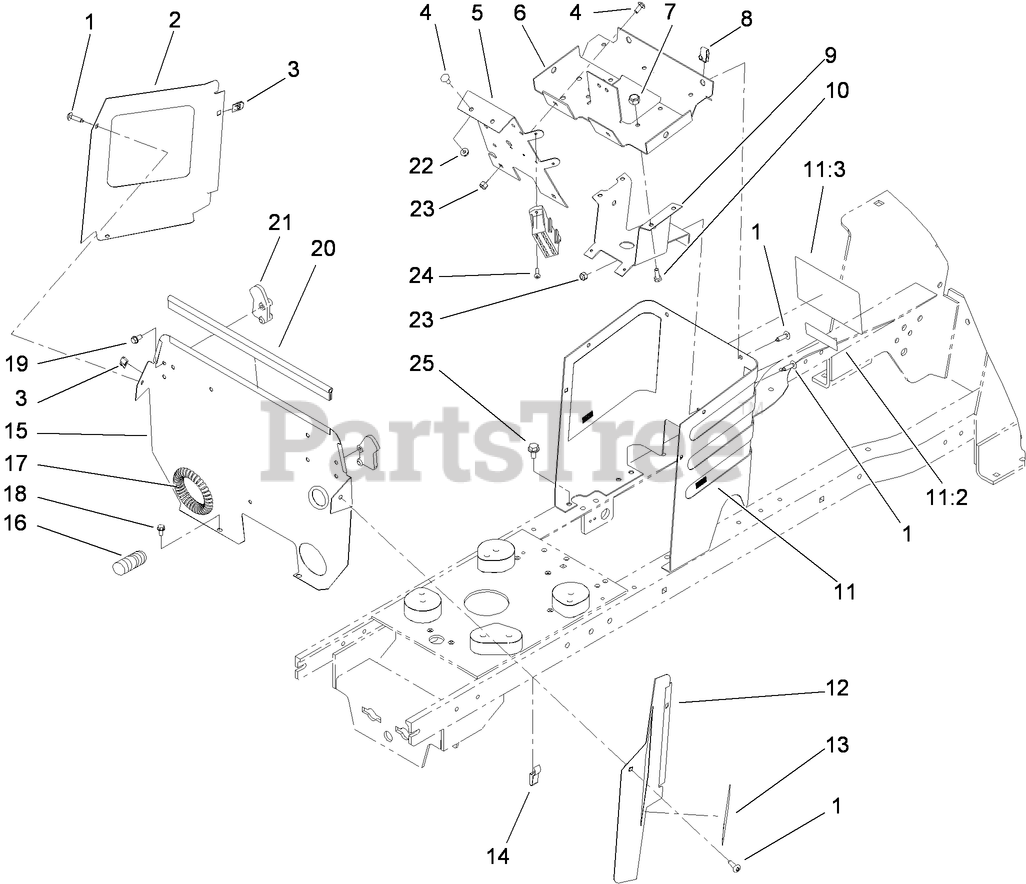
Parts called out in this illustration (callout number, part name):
1	SCREW-HH
2	RH SIDE COVER ASM
4	SCREW-CARR
5	PANEL-SUPPORT, DASH
6	SUPPORT-DASH
7	NUT-HEX
9	BRACKET-COLUMN, LOWER
10	SCREW-HH
11	HOODSTAND W/DECALS ASM
11:2	DECAL-INSTRUCTION
11:3	DECAL-DANGER
12	LH COVER ASM
14	CLAMP-CASING
17	COVER-SHAFT, DRIVE
18	SCREW-HWH
19	SCREW-PLASTITE
20	TRIM-SEAL, FIREWALL
21	LATCH-HOOD
22	NUT-KEPS
23	NUT-LOCK, NI
24	SCREW-PPHTF
25	SCREW-HWHTF
